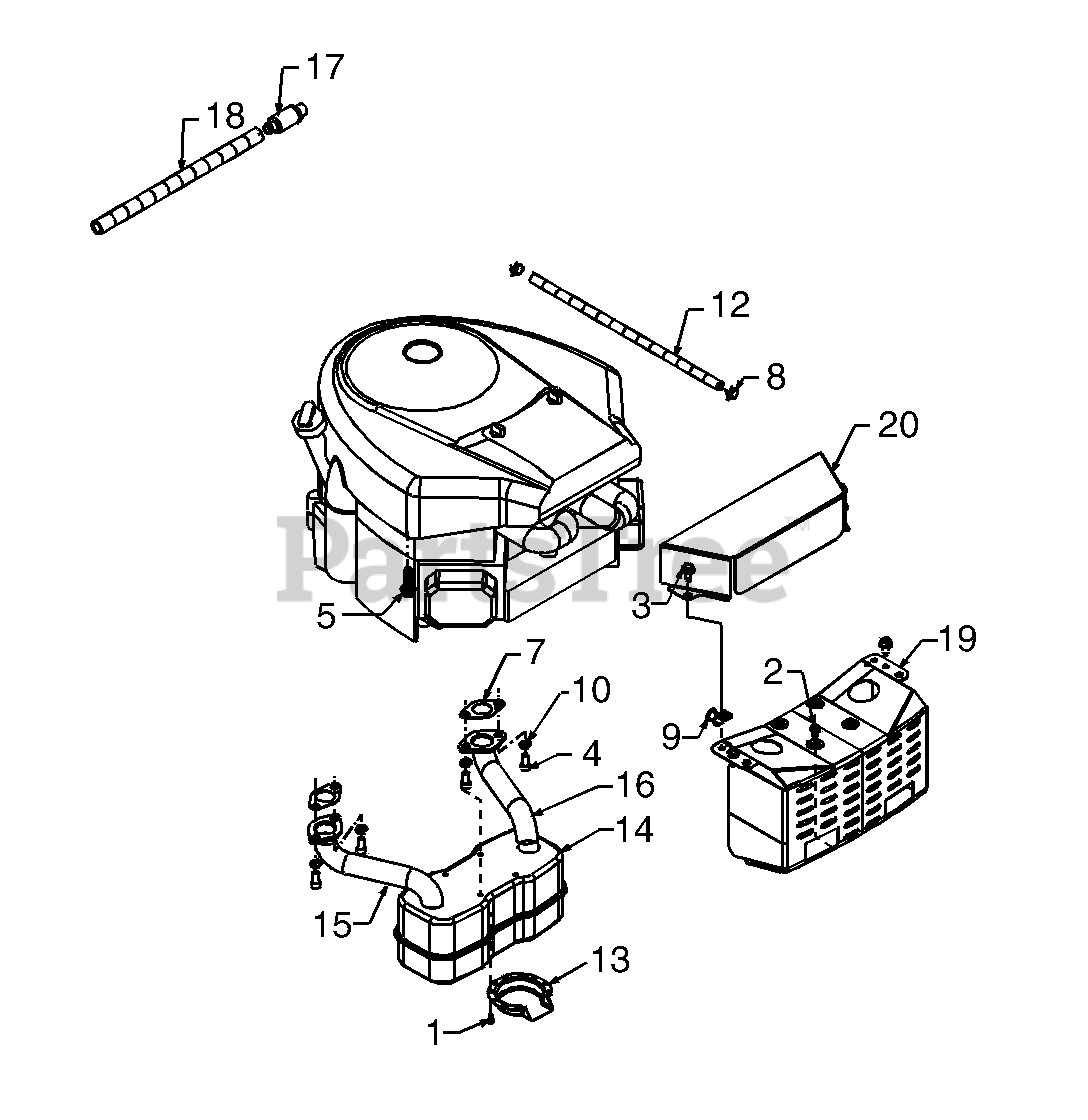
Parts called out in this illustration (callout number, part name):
1	Hex Tap Scr. #8-32 x .38" Lg.
2	Hex Wash. TT-Tap Scr. 1/4-20 x 5" Lg.
3	Hex Wash. TT-Tap Scr. 5/16-18 x .62" Lg.
4	Socket Head Scr. 5/16-18 x .62"
5	Hex TT-Tap Scr. 3/8-16 x 1.25"
7	Exhaust Gasket
8	Hose Clamp
9	Clamp
10	L-Wash. 5/16" I.D.
12	Fuel Line 12" Lg.
13	Muffler Deflector
14	Muffler
15	Exhaust Pipe-R.H.
16	Exhaust Pipe-L.H.
17	Oil Drain
18	Oil Drain Hose
20	Heat Shield
